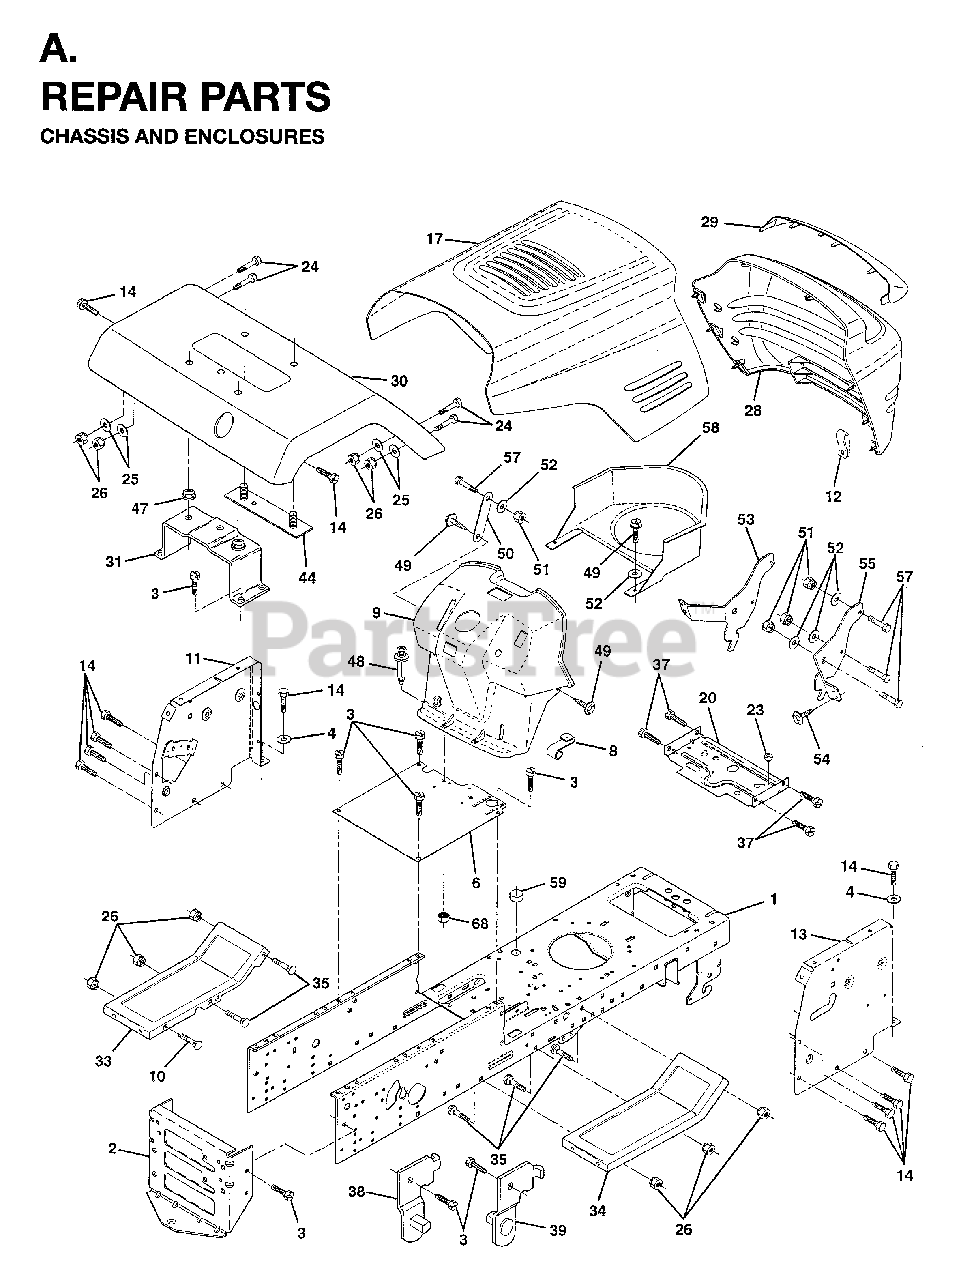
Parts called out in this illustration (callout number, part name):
2	STRETCH DRAWBAR
4	WASHER
6	SADDLE LT FENDER
8	CLIP,INSULATOR
11	PANEL PNT DASH LH
13	PANEL DASH RH
20	PLATE MTG BATTERY FUEL TAND
23	GROMMET T
25	WASHER
26	LOCKNUT
31	FENDER BRKT
38	BRACKET LH PIVOT
39	BRACKET RH PIVOT
47	NUT-PUSH YT
48	RIVET PUSH
50	BRACE
51	NUT.CROWNLOCK.1/4
58	AIR DUCT P/L/LT
59	SNAP BUSHING T
68	NUT.CROWNLOCK.1/4
